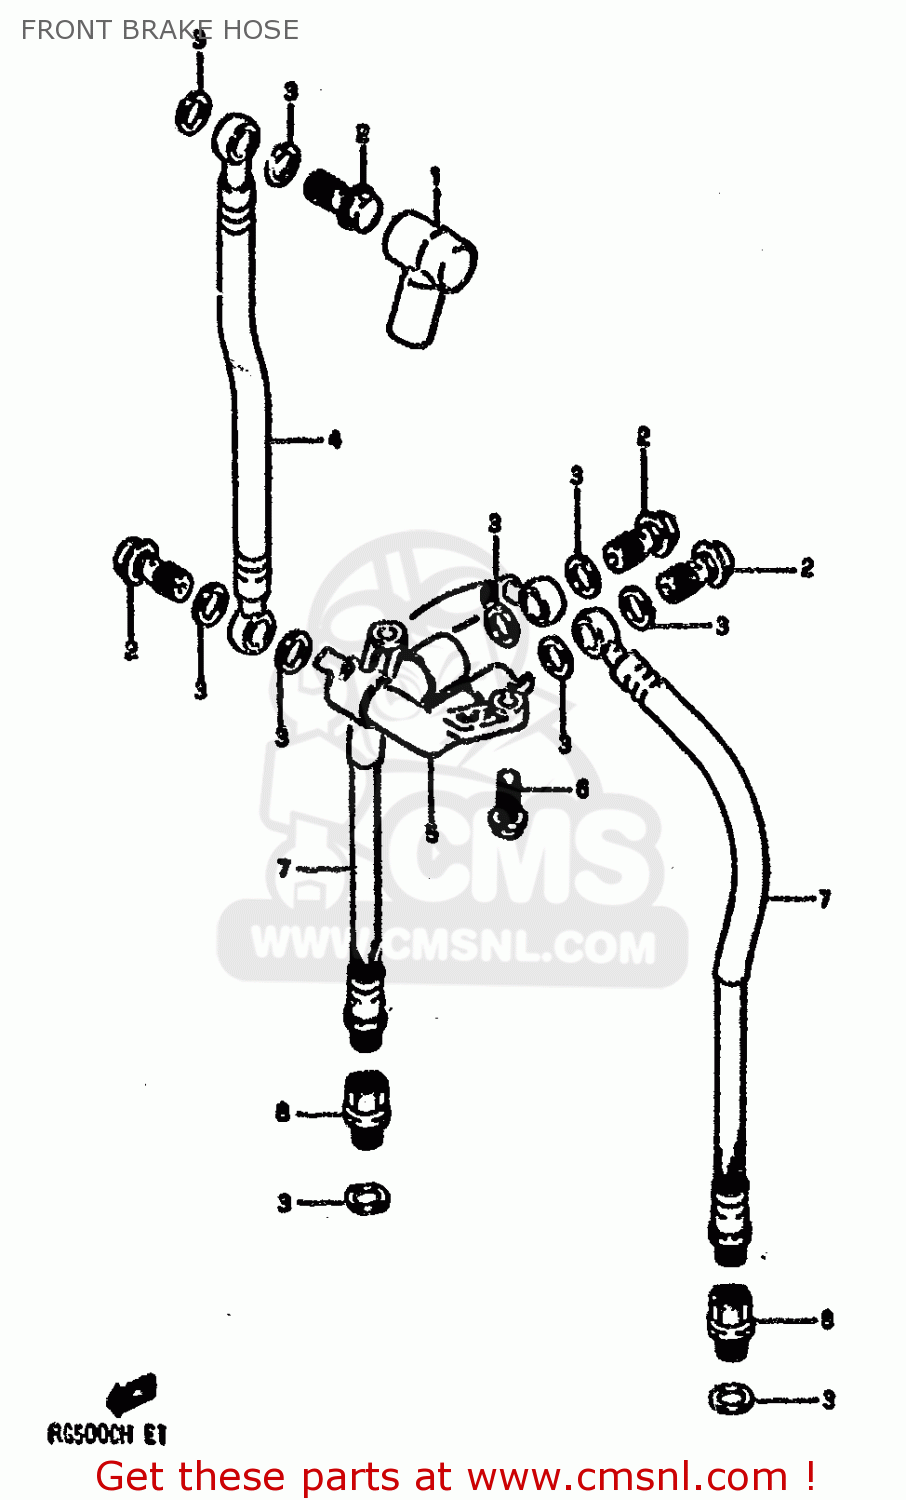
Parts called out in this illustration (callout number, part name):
1	BOOT
2	BOLT UNION
3	WASHER(10X15X1.5)
4	HOSE,FRONT BRAKE NO.1
5	BRAKE HOSE JOIN
6	BOLT,REAR
7	JOSE,FRONT BRAKE NO.2
8	ADAPTER,BRAKE HOSE
